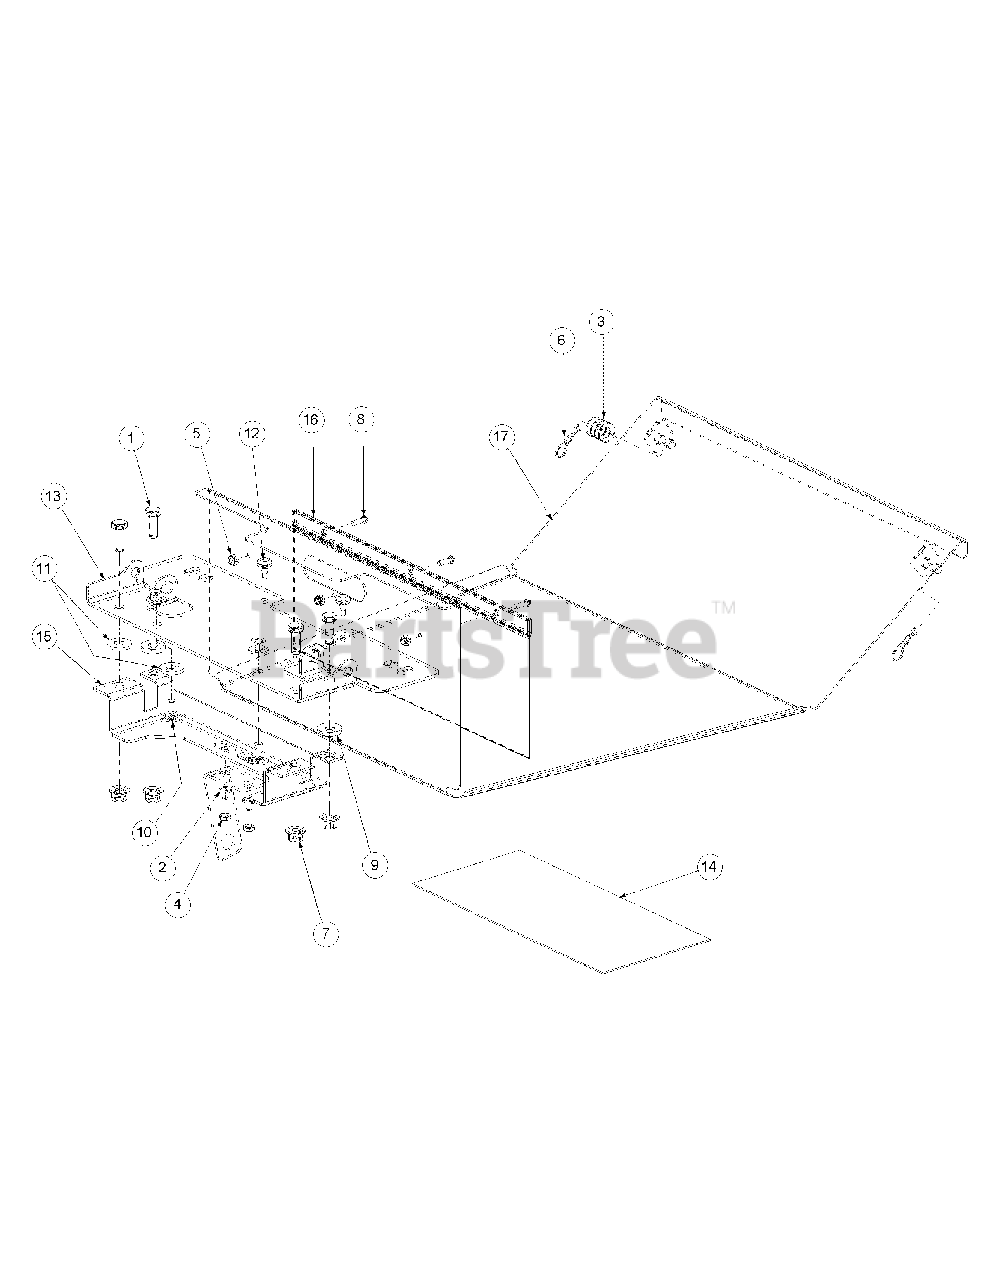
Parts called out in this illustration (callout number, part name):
1	Hex Cap Screw, 3/8-16, x 1
2	Lock Washer, 1/4
3	Washer
4	Hex Cap Screw, 1/4-20, .75
5	Lock Nut, Nylon Insert, 10-32
6	Hair Pin, 3/8-1/2
7	Hex Nut, Flange Lock, 3/8-16
8	Screw, Phillips Head, Machine, 10-32 x 5/8
9	Washer
10	Carriage Bolt, 3/8-16 x .75 Long
11	Flat Washer, .406 ID x 1.0 OD x .105
12	Rubber Bumper, .62 OD x .22 Thick
14	Label, Belt Routing and Lubrication
15	Support, Seat Bracket
16	Bag, Debris Storage
17	Floor Panel Assembly
